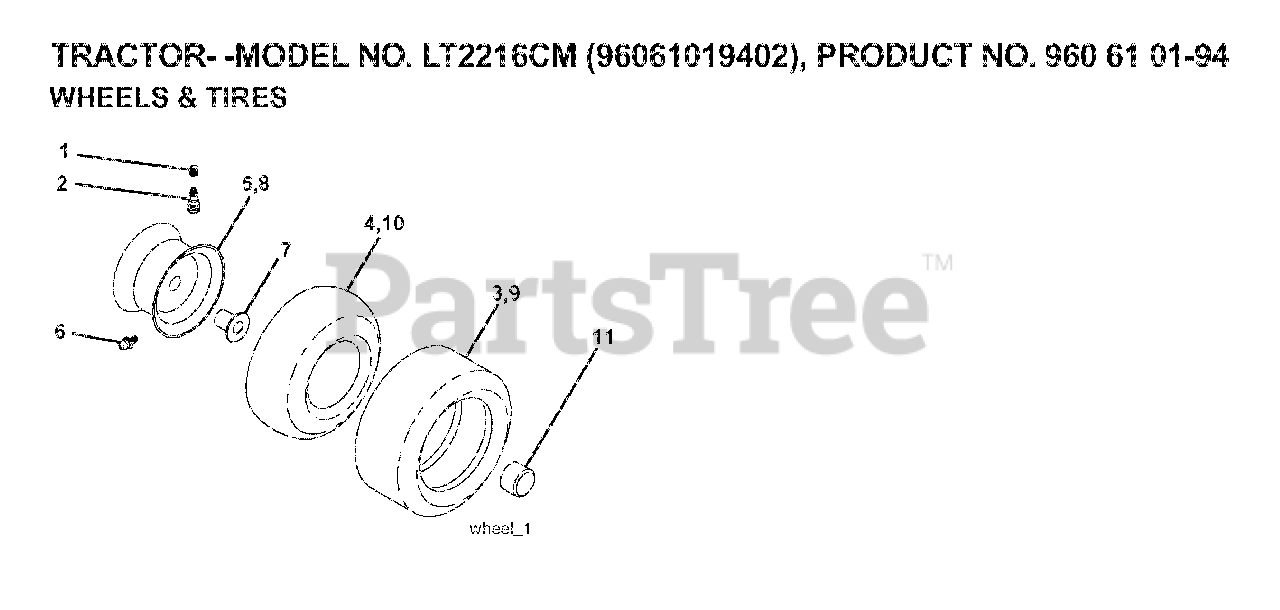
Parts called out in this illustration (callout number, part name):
1	VALVE CAP
2	VALVE STEM LT
3	TIRE HEAVY DUTY
4	TUBE.5.3/4.5/6
5	RIM ASM 6" FRONT SILVER
6	FITTING LT
7	BEARING T
8	RIM ASM 8" REAR SILVER
9	TIRE HEAVY DUTY
10	TUBE
11	CAP, AXLE BLK
